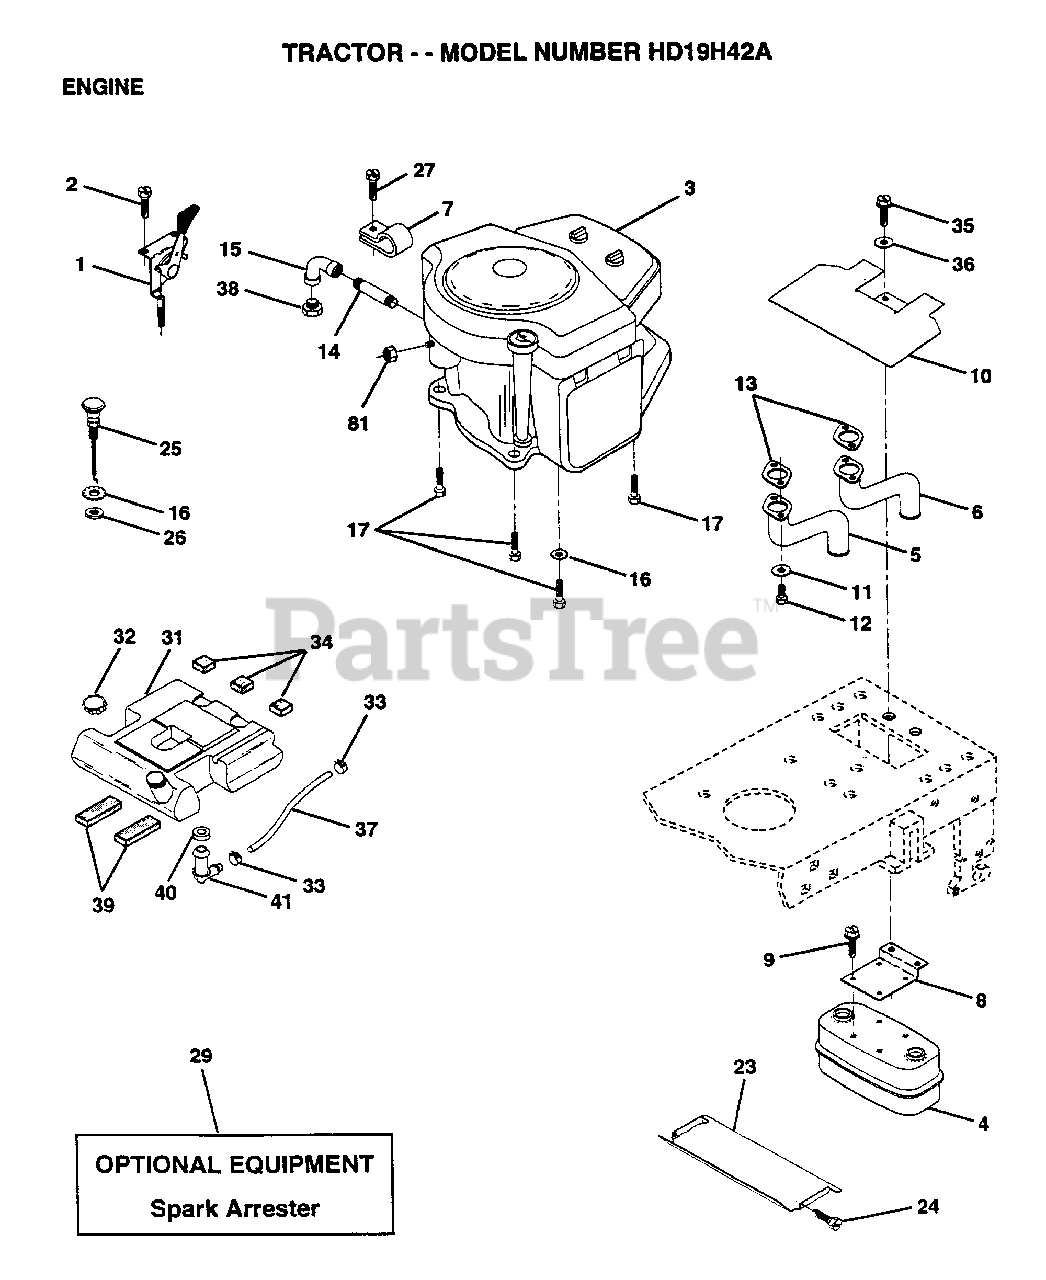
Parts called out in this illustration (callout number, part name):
1	CONTROL.TRTL.37
2	SCREW LT
5	EXHAUST.B&S.18.LH
6	EXHAUST.B&S.18.RH
7	CLAMP.TUBE.DBL.EN
8	BRACKET MUFFLER
9	SCREW ST
10	SHIELD.HEAT.
11	LOCKWASHER
14	PIPE NIPPLE LT
15	ELBOW
16	LOCKWASHER
17	SCREW
23	HEAT SHIELD
24	SCREW
25	"CONTROL.CHOKE.51"""
27	SCREW.10-24X1/2
32	CAP ASM FUEL
33	HOSE CLAMP
34	PAD-SPACER LT
35	SCREW
36	WASHER
37	FUEL LINE T
39	PAD IDLER TI
40	BUSHING OUTLET T
41	STEM.TANK.FUEL
81	NUT
